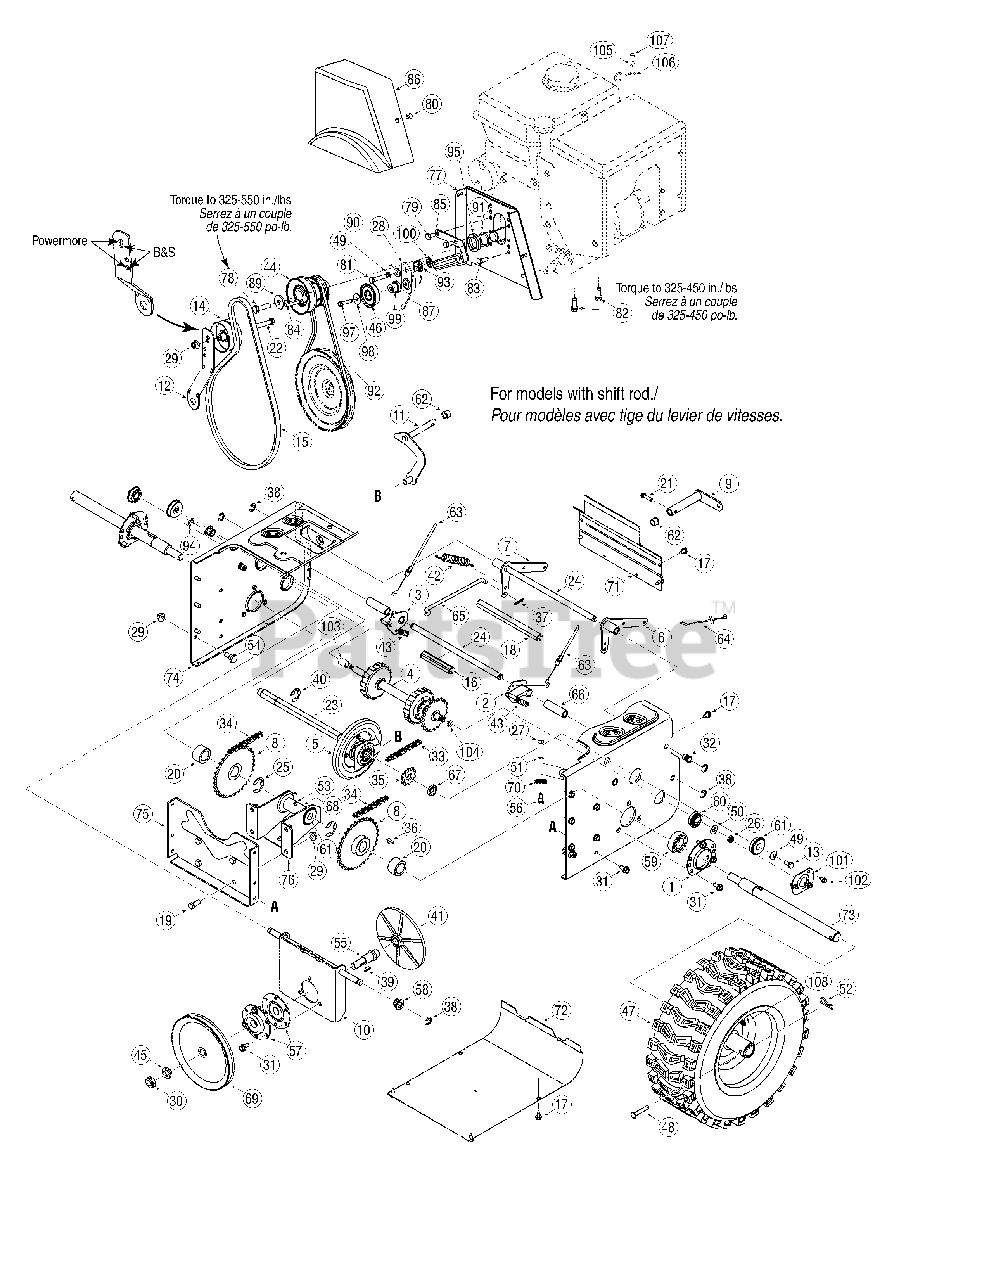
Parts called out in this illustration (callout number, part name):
1	Bearing Housing
2	LH Dog Assembly
3	RH Dog Assembly
4	Steering Shaft Assembly
5	Wheel Ass’y Bearing 6.0" OD
5	Friction Wheel Bonded
5	Hex Wash. Hd. TT Scr. 1/4-14 x .625
6	Actuator Auger Bracket Ass’y
7	Actuator Drive Bracket Ass’y
8	32T Sprocket Ass’y
9	Shift Arm Ass’y
10	Friction Drive Support
11	Shift Ass’y Rod
12	Auger Idler Bracket
13	Hex L-Bolt 5/16-18 x .62
14	Flat Idler Pulley
15	V-Belt 4L x 44.6" Lg.
16	Spacer .51 ID x 3.66" Lg.
17	Hex Wash Hd TT Scr. 1/4-20 x .625
18	Spacer .51 ID x 7.895" Lg.
19	Hex Hd. C-Sunk Scr. 3/8-16 x .880 Gr. 5
20	Spacer 1.0 ID x 1.5" Lg.
21	Hex Bolt 1/4-20 x 1.00
22	Hex Screw 3/8-16 x 1.75
23	Hex Drive Shaft
24	Actuator Shaft
25	Retaining Ring
26	Hex Nut 3/8-24
27	Hex Nut 1/4-28
28	Drive Idler Bracket
29	Flange L-Nut 3/8-16 Gr. F Nylon
30	Hex Jam Locknut 5/8-18 Gr. 5 Nylon
31	TT Screw, 5/16-18 x .75
32	Nut Insert 3/8-16 UNC
33	#41 Chain 1/2" pitch x 36 links- End less
34	#420 Chain 1/2" pitch x 40 links-End less
35	10T Sprocket #41 x .500
36	Woodruff Key
37	Int. Cotter Pin 5/16 DIA
39	No. 61 Hi-Pro Key 3/16 x 5/8
40	Retaining Ring E-Type .875 dia.
41	Aluminum Drive Plate
42	Idler Extension Spring
43	Extension Spring .47 OD x 2.03 Lg.
44	Pulley, Dbl (w/357 cc Powermore engine)
45	Lockwasher 5/16 ID
46	Idler Pulley Ass'y
47	LH Wheel Ass'y Comp. 16 x 6.5 x 8 X-Trac
47	RH Wheel Ass'y Comp. 16 x 6.5 x 8 X-Trac
48	Clevis Pin
49	Cupped Washer .345 ID x .88 OD x .06
50	Flat Washer .385 ID x .87 OD x .06
51	L-Wash 1/4 ID
52	Int. Cotter Pin
54	Shld. Scr. .500 Dia. x .335" Lg.
55	Drive Plate Spindle
56	Hex Shld.Scr.1/4-28 x .375
57	Bearing Hsg. Ass’y.
58	Hex Flange Bearing
59	Self Aligning brg. 1.0 ID
60	Ball Bearing .5625 ID x 1.3750 x .4375
61	Ball Bearing w/snap ring
62	Flange Bushing .500 ID x .627 OD
63	Steering Cable
64	Auger Idler Cable
65	Drive Clutch Rod
66	Split Spacer 1/2 x 5/8 x 2.69
67	Spacer .625 ID x 1.0 OD x .23
68	Spacer .6725ID x 1.125OD x 2.485
69	1/2" "V" Pulley .625 ID x 7.50 OD
70	Cable Guide Roller
73	Axle .995 x 12.6" Lg. (28")
73	Axle.995 x 14.10" Lg (30" & 33")
73	Axle .995 x 20.4" Lg. (45")
75	Frame Support Bracket
76	Axle Brg. Support Bracket
77	Belt Cover Bracket
78	Hex Screw 3/8-24 x 1.25 Gr. 8 (Powermore)
79	Hex Screw 5/16-24 x .75 Gr. 5
80	Hex Wash HD S-Tapp Scr 5/16-18 x .50
81	Hex HD. Cap Scr. 5/16-24 x 1.5 Lg. Gr. 5
82	Hex Wash HD Tap Scr 3/8-16 x 1.00
83	Shoulder Screw .50 x .145: 5/16-24
84	Square Key 1/4 x 1/4 x 1.50" Lg.
85	Belt Keeper Bracket
86	Belt Cover
87	Torsion Spring .850 x 3.33" Lg.
89	Flat Washer .406 ID x 1.25 OD x .160
90	Shoulder Spacer .3175 x .5 x .094
91	Spacer 1.155 ID x 1.5 OD x 0.150 (w/Powermore)
92	V-Belt 3/8 x 34.4" Lg. (B&S)
92	V-Belt 3/8 x 36.68" Lg. (Powermore)
93	Shoulder Spacer .340 x 1.0
94	Speed Nut .50
95	Spacer 1.004 x 1.375 x .25 (w/357 cc Powermore)
97	Hex Bolt 1/4-20 x 1.25
98	Flat Washer .265 ID x 1.0 OD x 0.030 HT
99	Shoulder Spacer
100	Push on Nut
101	Bearing Retaining Bracket
102	Hex Wash S-Tapp Scr 1/4-20 x .50
103	Spacer .566 ID x .87 OD x 1.25
104	Spacer .566 ID x .87 OD x 0,190
105	Flat Washer .330 ID x .630 OD x .0635
106	Cable Guide
107	Hex Hd. Cap Scr. MB-1.25:20 Gr. 8
108	Air Valve
